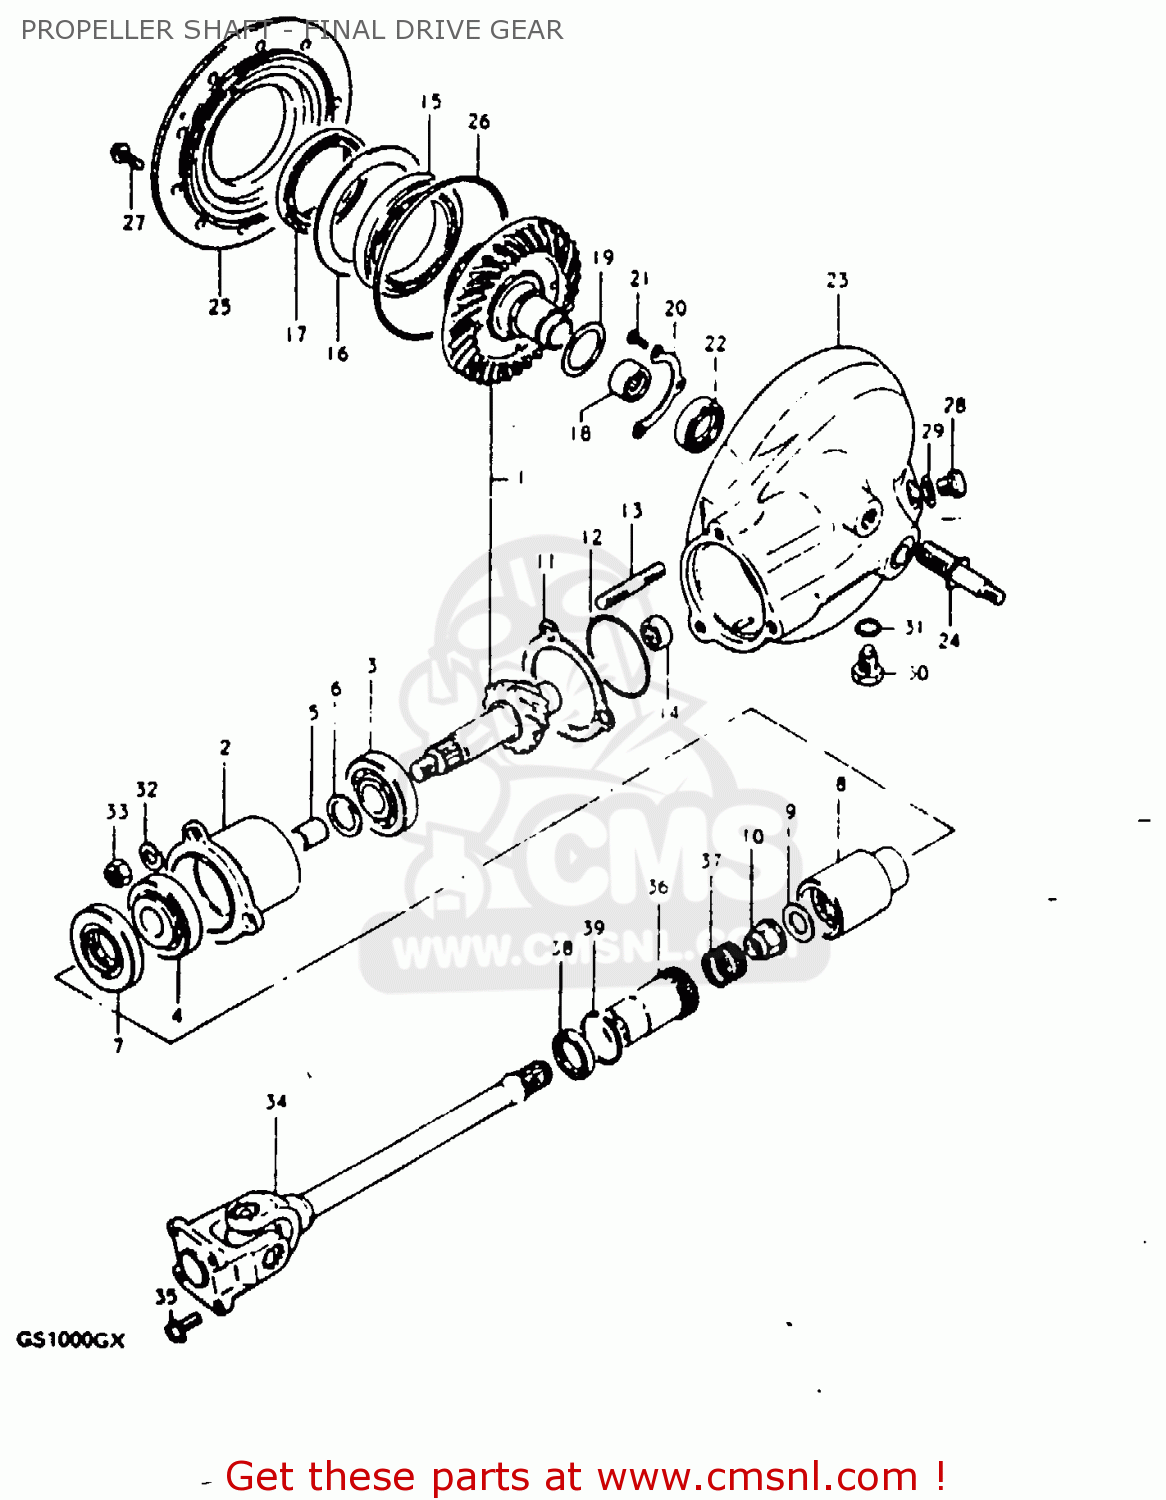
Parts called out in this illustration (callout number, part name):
1	GEAR SET,FINAL BEVEL
2	HOUSING,DRIVE GEAR
3	BEARING(25X52X19.25)
4	BEARING
5	SPACER (25.2X30X3.5)
6	SHIM (25X30X2
7	SEAL,OIL(32X54X7)
8	GEAR,FINAL DRIVE
9	WASHER(14X29X4)
10	NUT
11	SHIM,DRIVE GEAR HOUSING
12	O RING(D:2.4,ID:62.6)
13	STUD 10X30
14	BEARING(24X33X17)
15	BEARING(70X110X13)
16	SHIM,DRIVEN GEAR BEARING
17	SEAL,OIL(70X96X16)
18	BEARING(35X48X23.7)
19	SHIM,FINAL DRIVEN GEAR
20	RETAINER,FINAL DRIVEN GEAR BRG
21	SCREW 6X12
22	SEAL,OIL(30X42X7)
23	CASE ASSEMBLY,FINAL GEAR
24	STUD
25	CASE,FINAL GEAR BEARING
26	O-RING (D:3.1 ID:144.4)
27	BOLT
28	PLUG (14X12)
29	GASKET(14X19.2X2) (NAS)
30	PLUG
31	GASKET(14X19.2X2) (NAS)
32	LOCK WASHER
33	NUT
34	SHAFT ASSEMBLY,PROPELLER
35	BOLT(8X17)
36	COUPLING,PROPELLER SHAFT
37	SPRING
38	SEAL,OIL(30X40.5X5.5)
39	CIRCLIP
